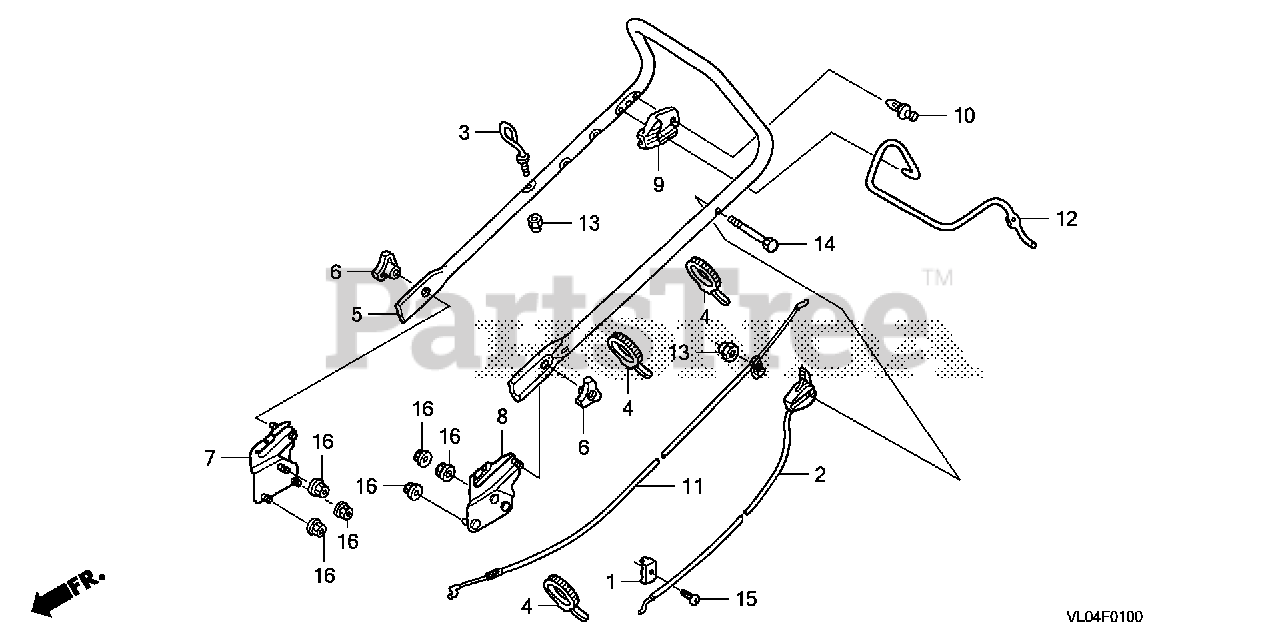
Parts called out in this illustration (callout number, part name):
1	HOLDER, CABLE
2	LEVER ASSY., THROTTLE
3	GUIDE, ROPE
4	TIE, CABLE (157.5MM)
5	PIPE, HANDLE *NH105* (MAT BLACK)
6	GRIP, HANDLE JOINT
7	STAY, R. HANDLE
8	STAY, L. HANDLE
9	STOPPER, LEVER
11	CABLE, BRAKE
12	LEVER, BRAKE
13	NUT, NYLON LOCK (6MM)
14	BOLT, HEX. (6X60)
15	SCREW, PAN (5X16)
16	NUT, FLANGE (8MM)
